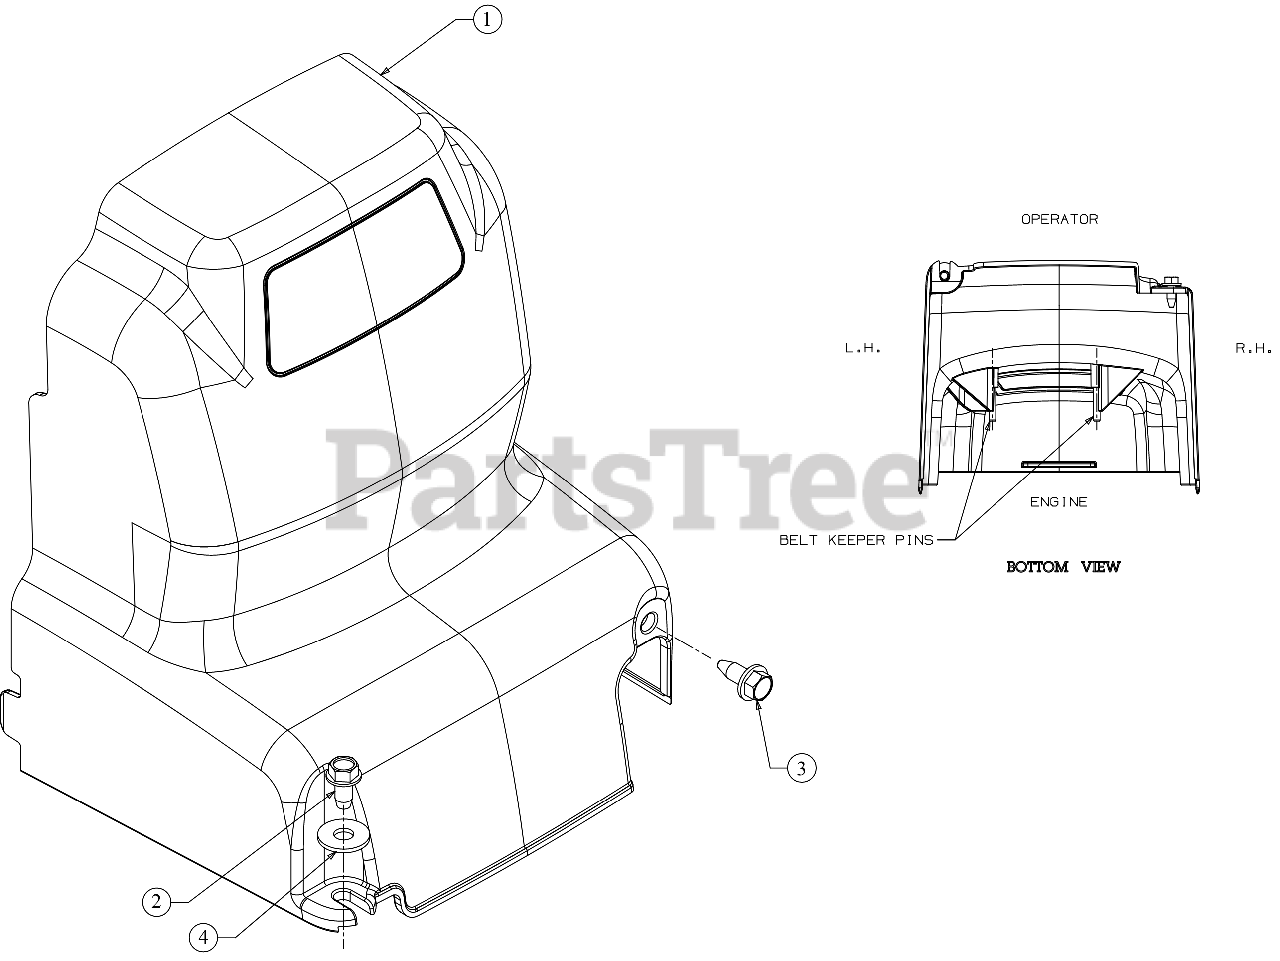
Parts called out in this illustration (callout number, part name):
1	COVER-BELT 400 SERIES TILLER
2	SCREW 1/4-20 X.500
3	SCREW 1/4-14 x .625
4	FLAT WASHER .28 ID x .74 OD x .063
